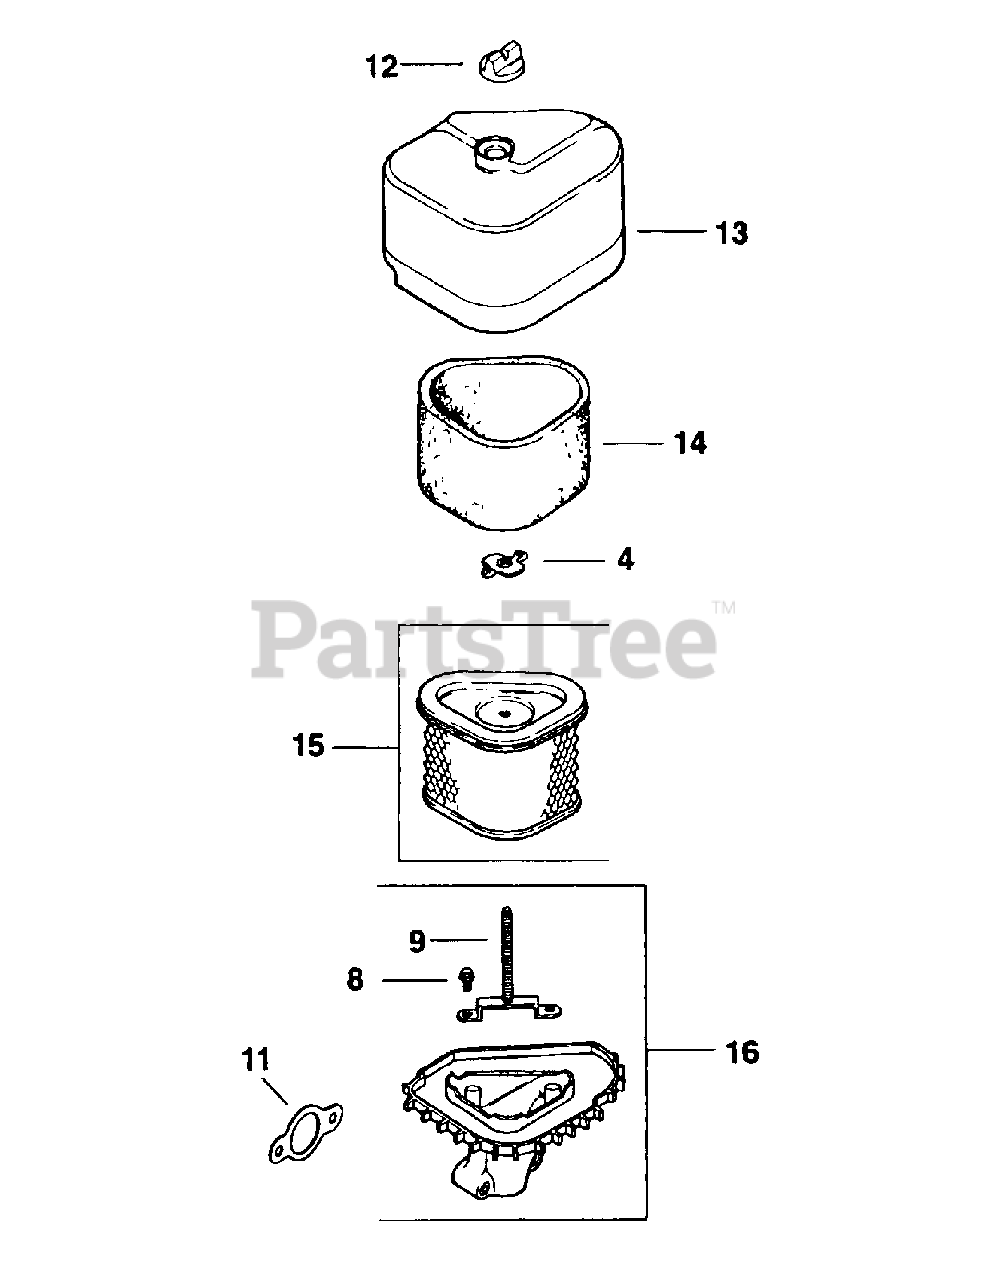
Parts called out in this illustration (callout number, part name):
4	Nut, Wing
8	Screw, Hex Cap #10 Hi-Lo
9	Stud, Mounting Plate
11	Gasket, Air Cleaner
12	Knob, Air Cleaner Cover
13	Cover, Air Cleaner
14	Precleaner
15	Elements, Air Cleaner & Precleaner
16	Base, Air Cleaner
